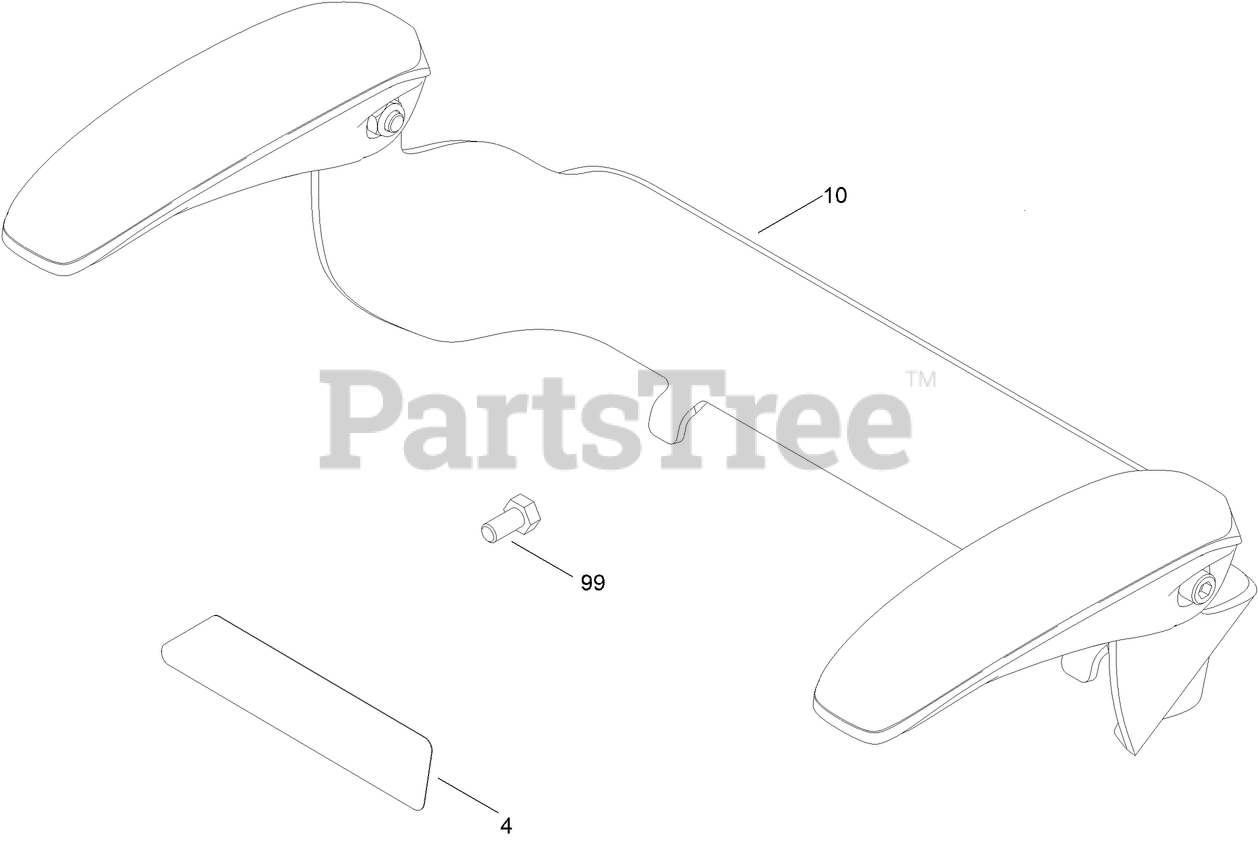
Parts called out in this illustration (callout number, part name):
4	DECAL ZXM5475
10	KIT-ARM REST
99	SCREW-HH
